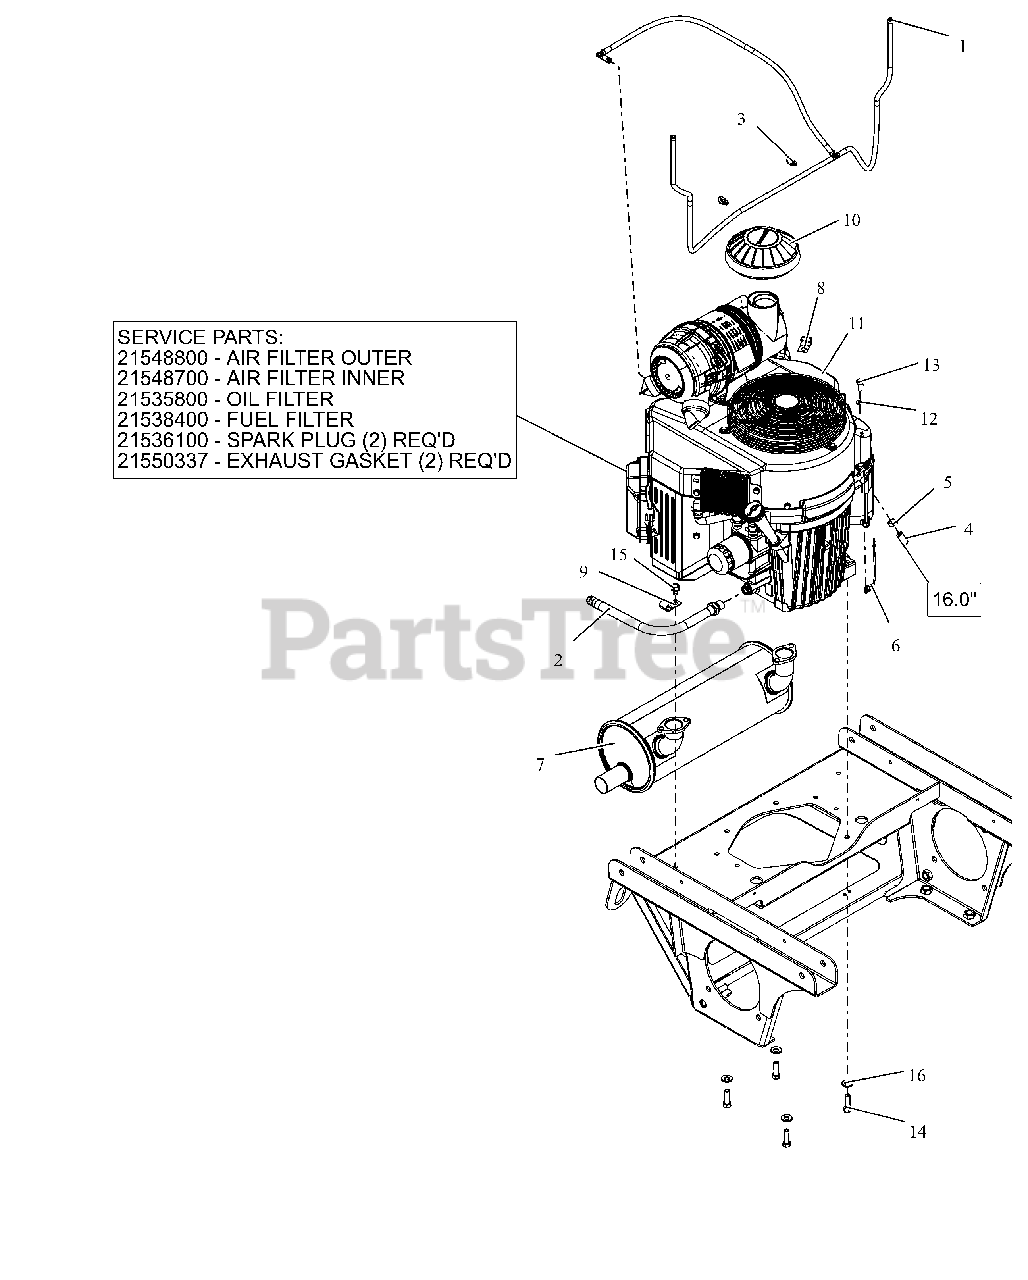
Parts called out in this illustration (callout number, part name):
1	ASM, VAPOR LINE
2	HOSE, OIL DRAIN
3	ROUTING CLIP (1/2" ID)
4	HOSE, .25 LOW-PERM BULK GAS
5	CLAMP, FUEL LINE
6	LEAD - STARTER SOLENOID
7	MUFFLER - 34HP KAWASAKI VERT.
10	CAP, AIR CLEANER INTAKE (2")
11	ENGINE-KAWASAKI FX921
11	FILTER, OUTER
11	FILTER, INNER - KAW
11	FILTER,OIL - KAW
11	FUEL FILTER - KAWASAKI
11	PLUG, SPARK
11	GASKET, EXHAUST (11061-7061)
12	WSHR,LK-REG .312X.078 ZCC
13	BLT, HEX M8-1.25X20 G8.8 ZCC
14	BLT, HEX .38-16X1.25 G5 ZCC NT
15	SCR,TAP .375-16X.50 HWH TR ZCC
16	WASHER, 3/8" SPRING DISC
